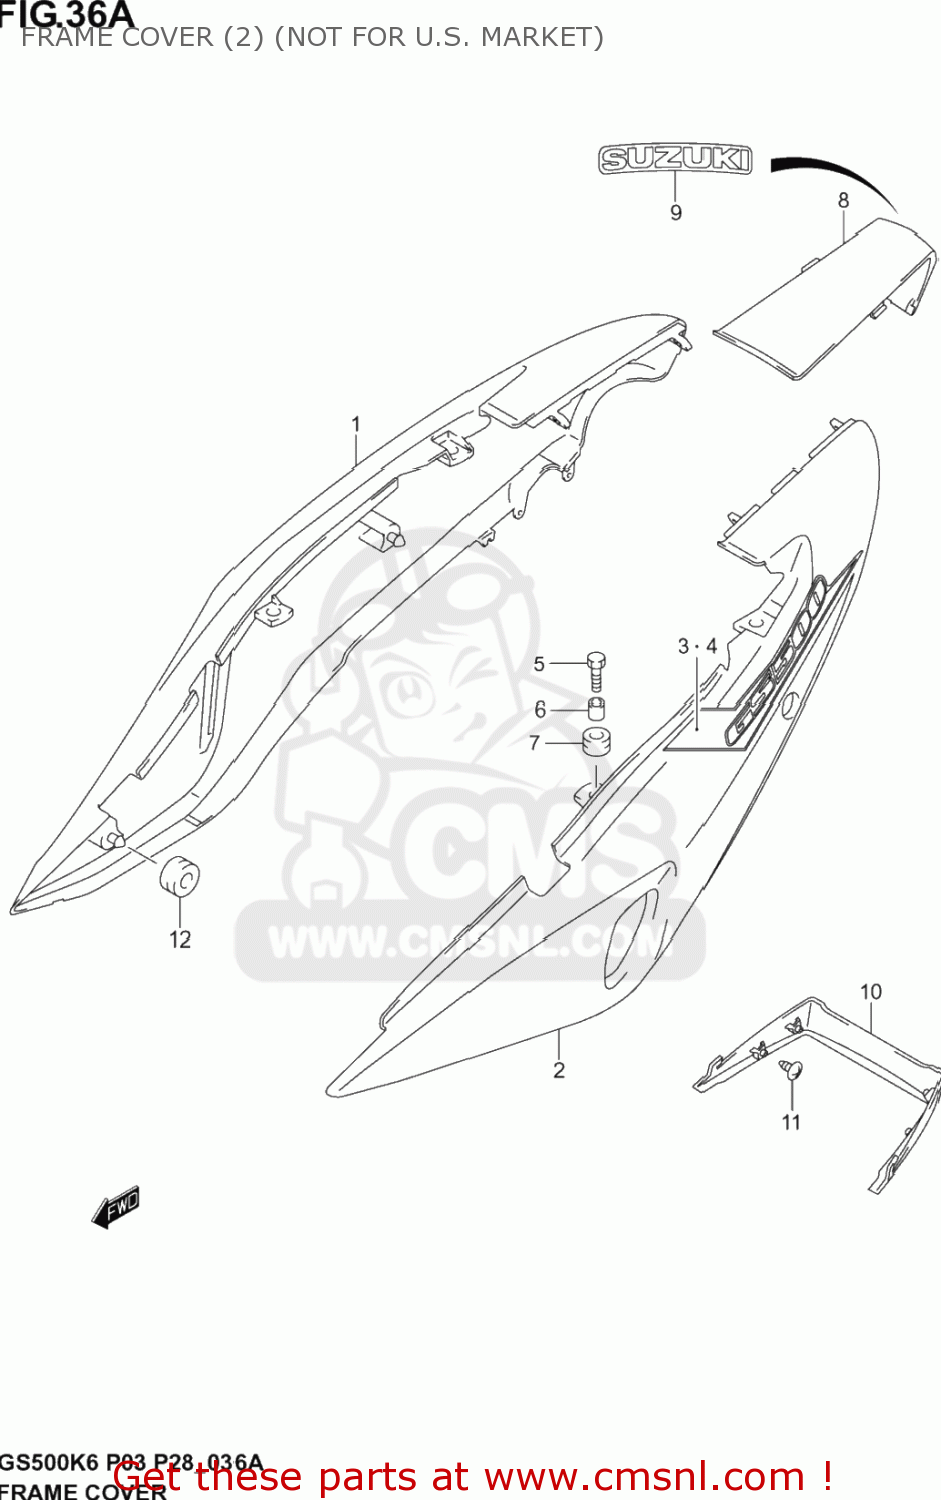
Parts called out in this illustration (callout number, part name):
1	COVER,FRAME
2	COVER, FRAME
3	TAPE,FRAMECOVE
4	TAPE,FRAMECOVE
5	BOLT(6X20)
6	SPACER(6.5X9X9)
7	CUSHION
8	COVER, CENTER
9	EMBLEM (SILVER
10	COVER LOWER
11	SCREW
12	CUSHION
